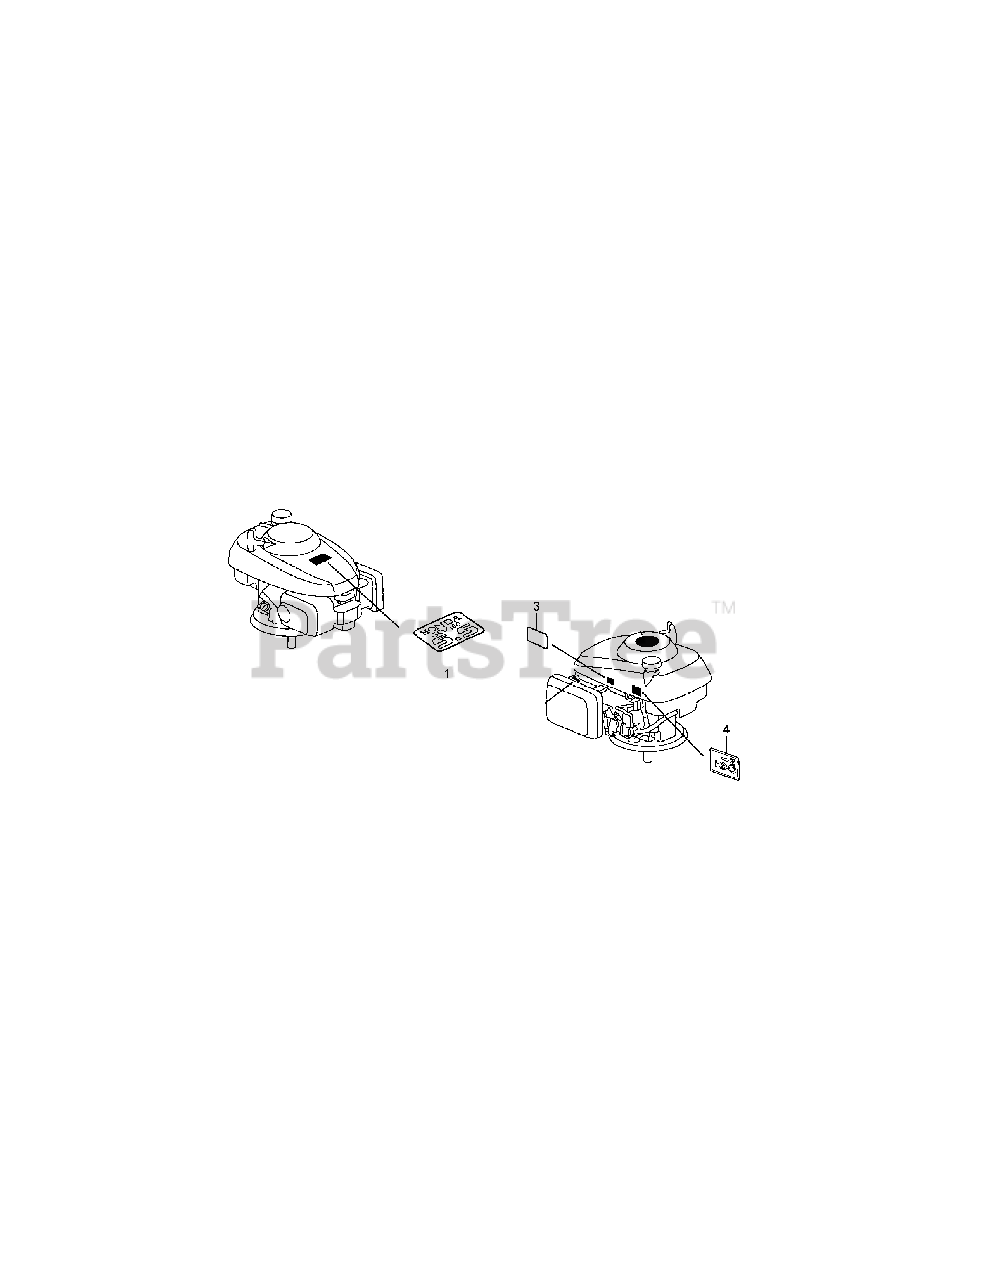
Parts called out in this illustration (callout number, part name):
1	Emblem Label
3	Warning Label
4	Choke Label
